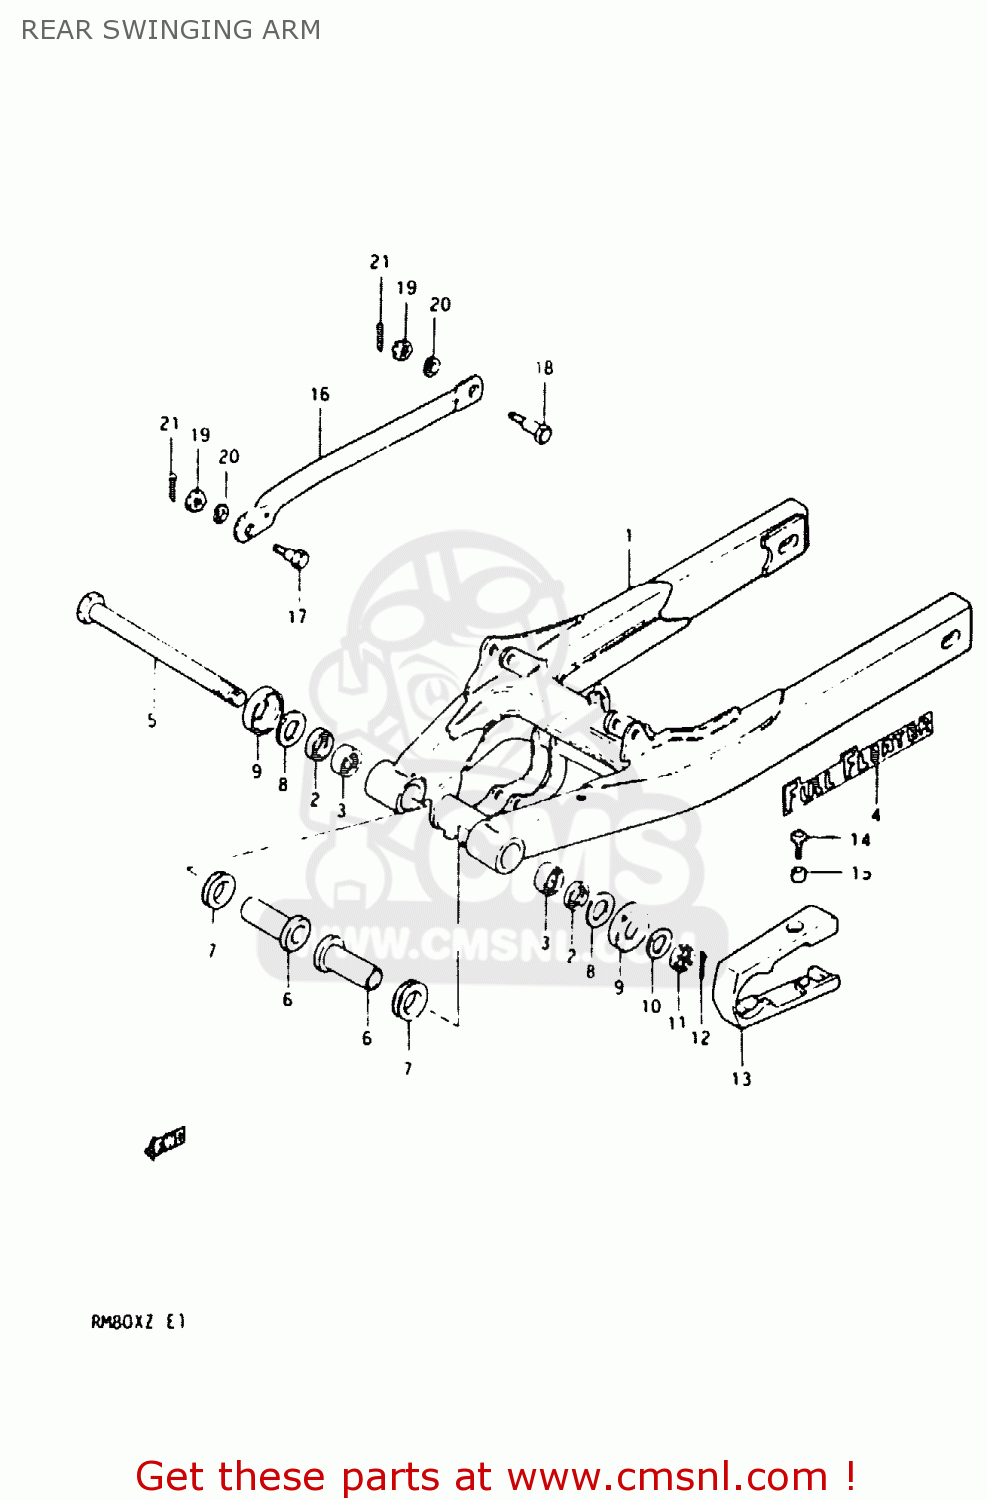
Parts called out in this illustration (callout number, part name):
1	SWING ARM ASSEMBLY,REAR
2	SEAL,OIL(17X24X3)
3	ROLLER BEARING (17X24X2
4	EMBLEM
5	SHAFT,REAR SWING ARM
6	SPACER,RR SWGARM PIVOT
7	SEAL,OIL(17X24X5)
8	WASHER
9	COVER,RR SWGARM DUST SEAL
10	WASHER
11	NUT, REAR AXLE
12	COTTER PIN
13	BUFFER,CHAIN TOUCH DEFLECTOR
14	SCREW,CHAIN TOUCH DEFEND
15	SPACER (5.5X8X4)
16	LINK,REAR TORQUE
17	BOLT(8X22)
18	BOLT(8X21)
19	NUT
20	LOCK WASHER
21	PIN 20X20
